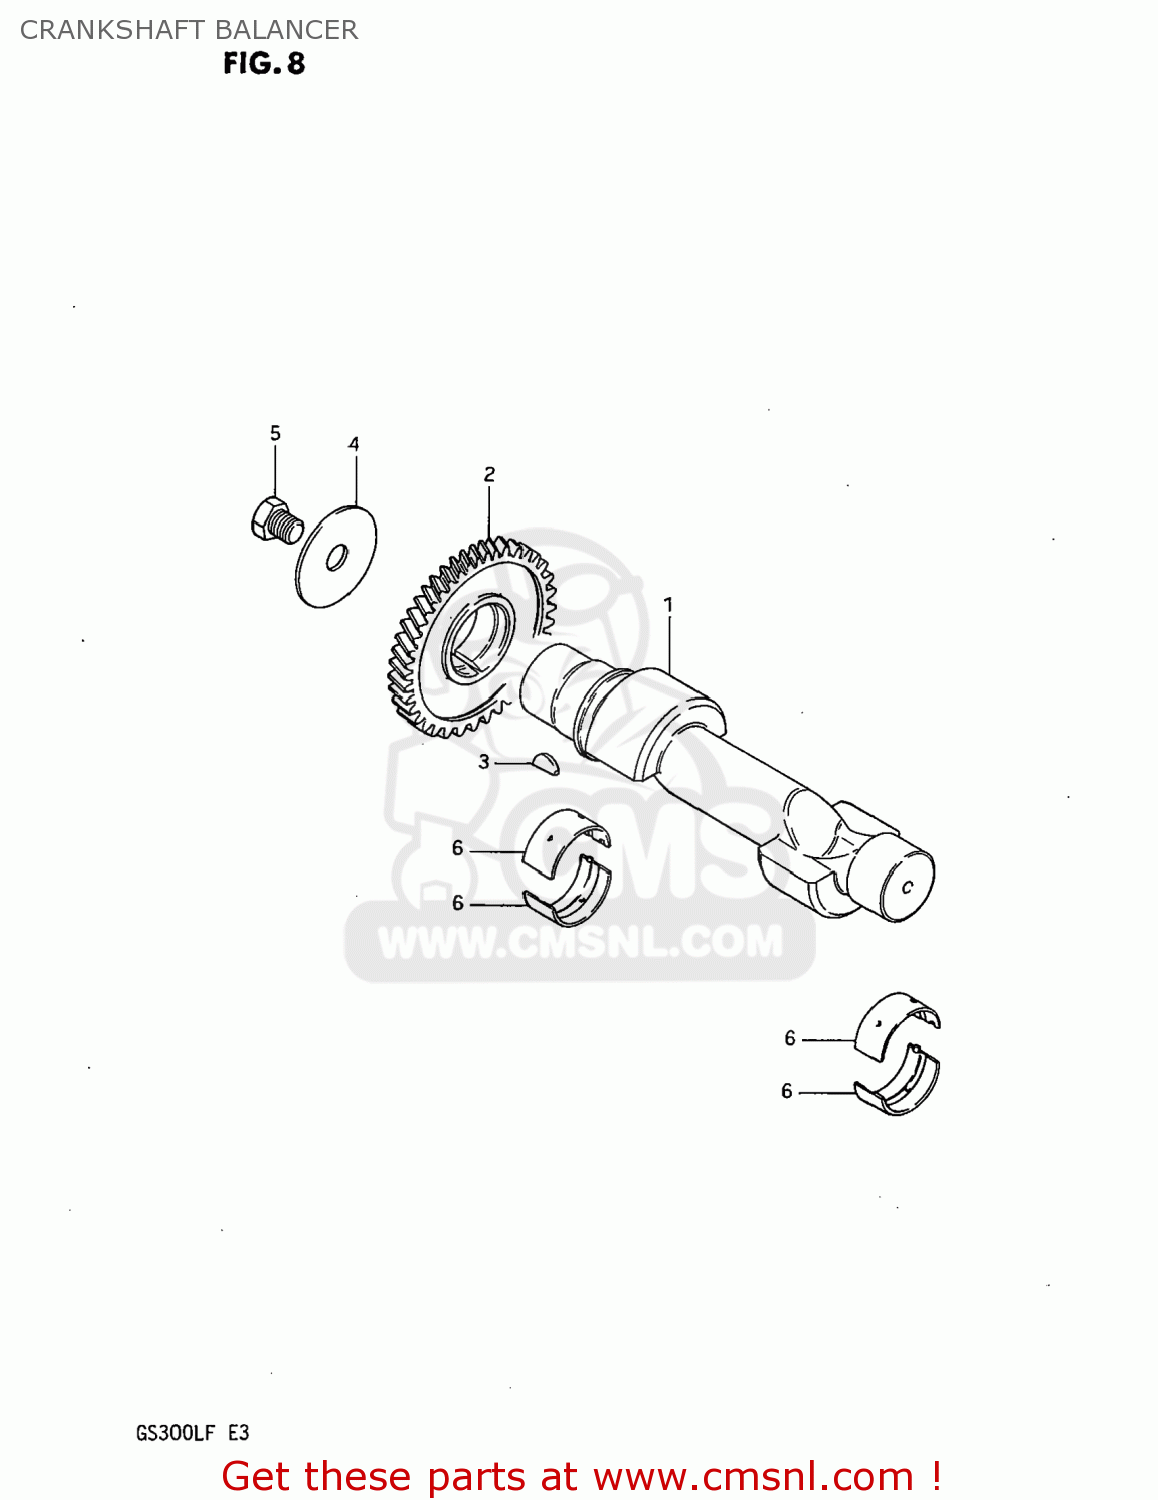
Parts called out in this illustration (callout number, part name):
1	BALANCER,CRANKSHAFT
2	GEAR,CRANK BALANCER
3	KEY 4MM
4	WASHER(12X50X3)
5	BOLT
6	BEARING (GREEN)
